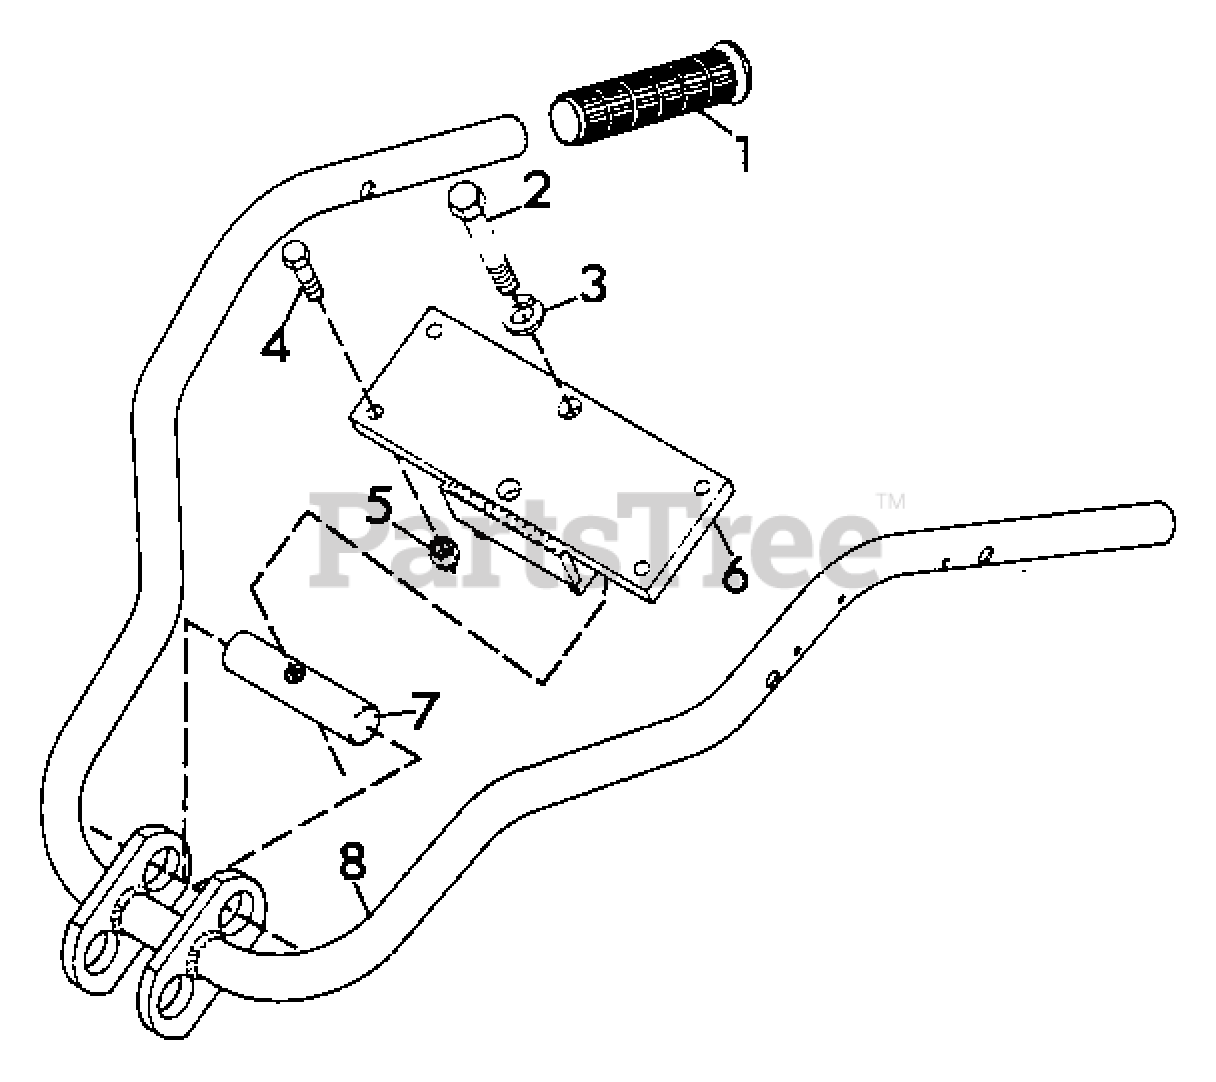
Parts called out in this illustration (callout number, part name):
1	Grip, Handlebar
2	Bolt, Hex 1/2-13x3.00 Gr. 8
3	Washer, Lock 1/2 Reg.
4	Bolt, Hex 3/8-16x1.25 Gr. 8
5	Nut, Lock 3/8-16
6	Weldment, Handlebar Bracket
7	Pin
8	Weldment, Handlebar
